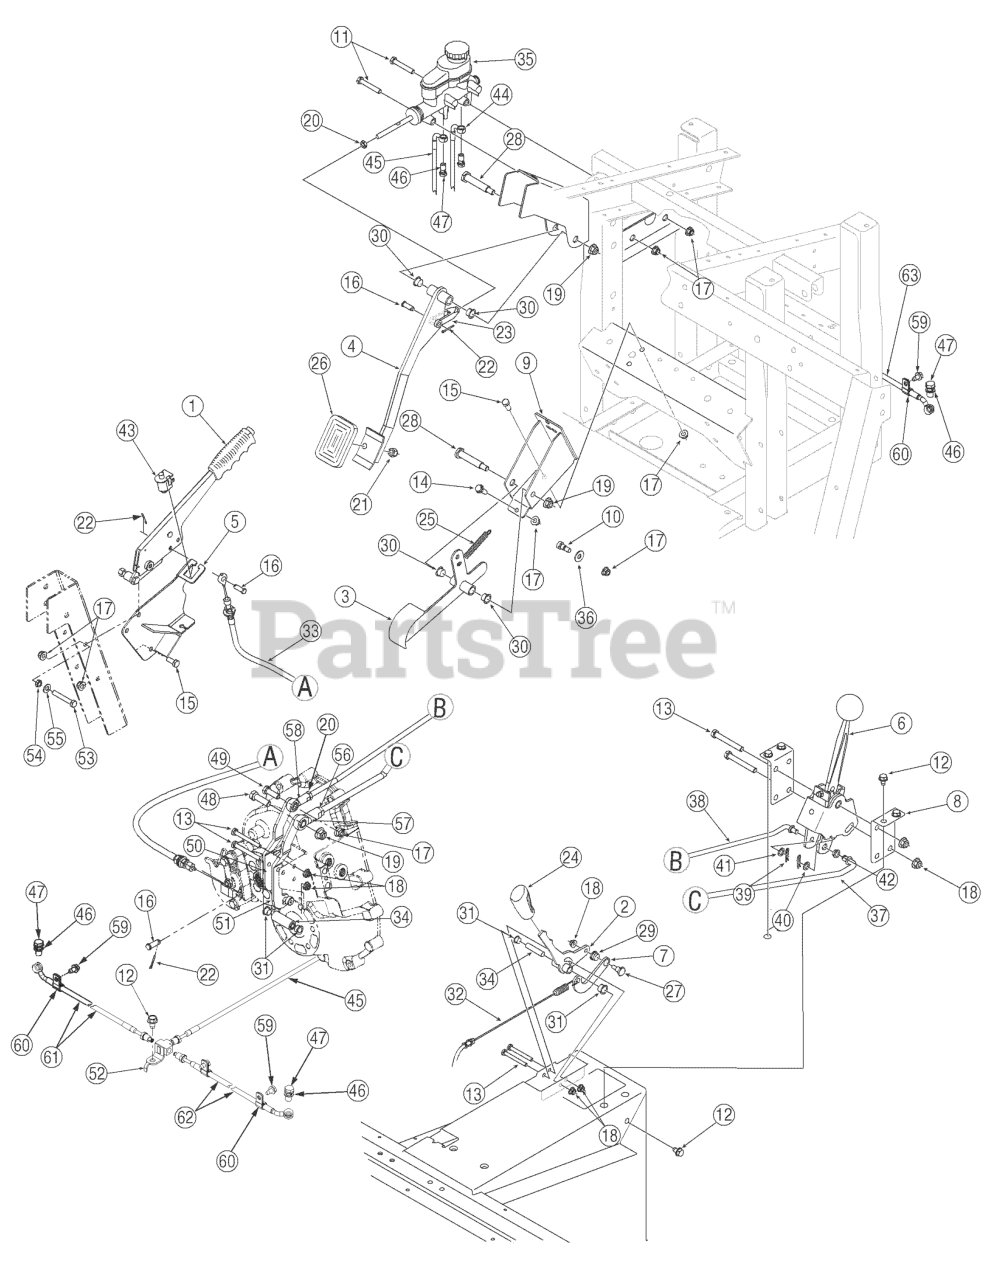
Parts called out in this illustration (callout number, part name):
1	Lvr Assembly, Brake
4	Pedal Assembly, Brake
6	Shft Assembly, Hurst
7	Plt, Pawl, Over Center
10	Scr, Shldr, .372 X .375, 5/16-18
11	Screw, 5/16-18, 2.00, Gr5, Patch
12	Scr, Tt, 5/16-18, 0.500
13	Screw, 1/4-20, 2.25, Gr5, Std
14	Scr, Tt, 5/16-18, 0.875
15	Screw, 5/16-18, .75, Gr5, Std
16	Pin, Clevis, 312 Od X 1.0"
17	Nut, Flglk, 5/16-18
18	Nut, Flglk, 1/4-20, Grf, Nylon
19	Nut, Flglk, 3/8-16, Grf, Nylon
20	Nut, Jam, 5/16-24, Gr5
21	Nut, Hexlk, 3/8-24, Gr2, Nylon
22	Pin, Cot, 3/32, 1.0
23	Yoke, 5/16-24
24	Handle, Selct
25	Spring, Extn, .38 Od X 3.6
26	Pad, Brake, Ped
27	Scr, Shldr, .375 x.380, 1/4-20
28	Scr, Shldr, .500 X 2.230, 3/8-16
29	Plastic Bushing .380 Id
30	Bearing, Flg, Nyliner, .500idx.34lg
31	Bearing, Flg, .375 X .580 X .250
32	Cable, Cont, Diff, Lock
33	Cable, Cont, Park, Brake, 4x4
34	Spcr, Pivot, Diff Lock
35	Cyl, Master, Tandem, Hayes
36	Wash, Flat, .349 X .879 X .063
37	Link, Shft, F N R
38	Link, Shft, Hi Lo
39	Pin, Cotter, .072 Dia. x 1.13
40	Wash, Flat, .385 X .62 X .063
41	Wash, Flat, .330 X .630 X .0635
42	Bearing, Flg, .377 Id
43	Switch
44	Hose, Brake, Master Cyl, Front
45	Hose, Brake, Master Cyl, Rear
46	Ftg, Banjo Ftg Bolt, M10 x 1.00
47	Ftg, Banjo Ftg Crush Wash, 10mm
48	Screw, 3/8-16 x 1.25
49	Screw, 5/16-18 x 1.00
50	Lvr., Assembly, Shift, Hi-Lo
51	Lvr., Assembly, Shift, F N
52	Ftg., Tee, 3-45 Deg Flare
53	Screw, Hex, 5/16-18 x 2.0
54	Nut, Hex Jam, 5/16-18 Gr5
55	Washer, Flat, .344 x .688
56	Nut, Hex Jam, 3/8-24 Gr2
57	Rod End, 3/8 ID
58	Rod End, 5/16 ID
59	Screw, Hex Tapp, 1/4-20 x .5
60	Clamp, Hose
61	Hose, Brake, Rear Left
62	Hose, Brake, Rear Right
63	Hose, Brake, Front Right
